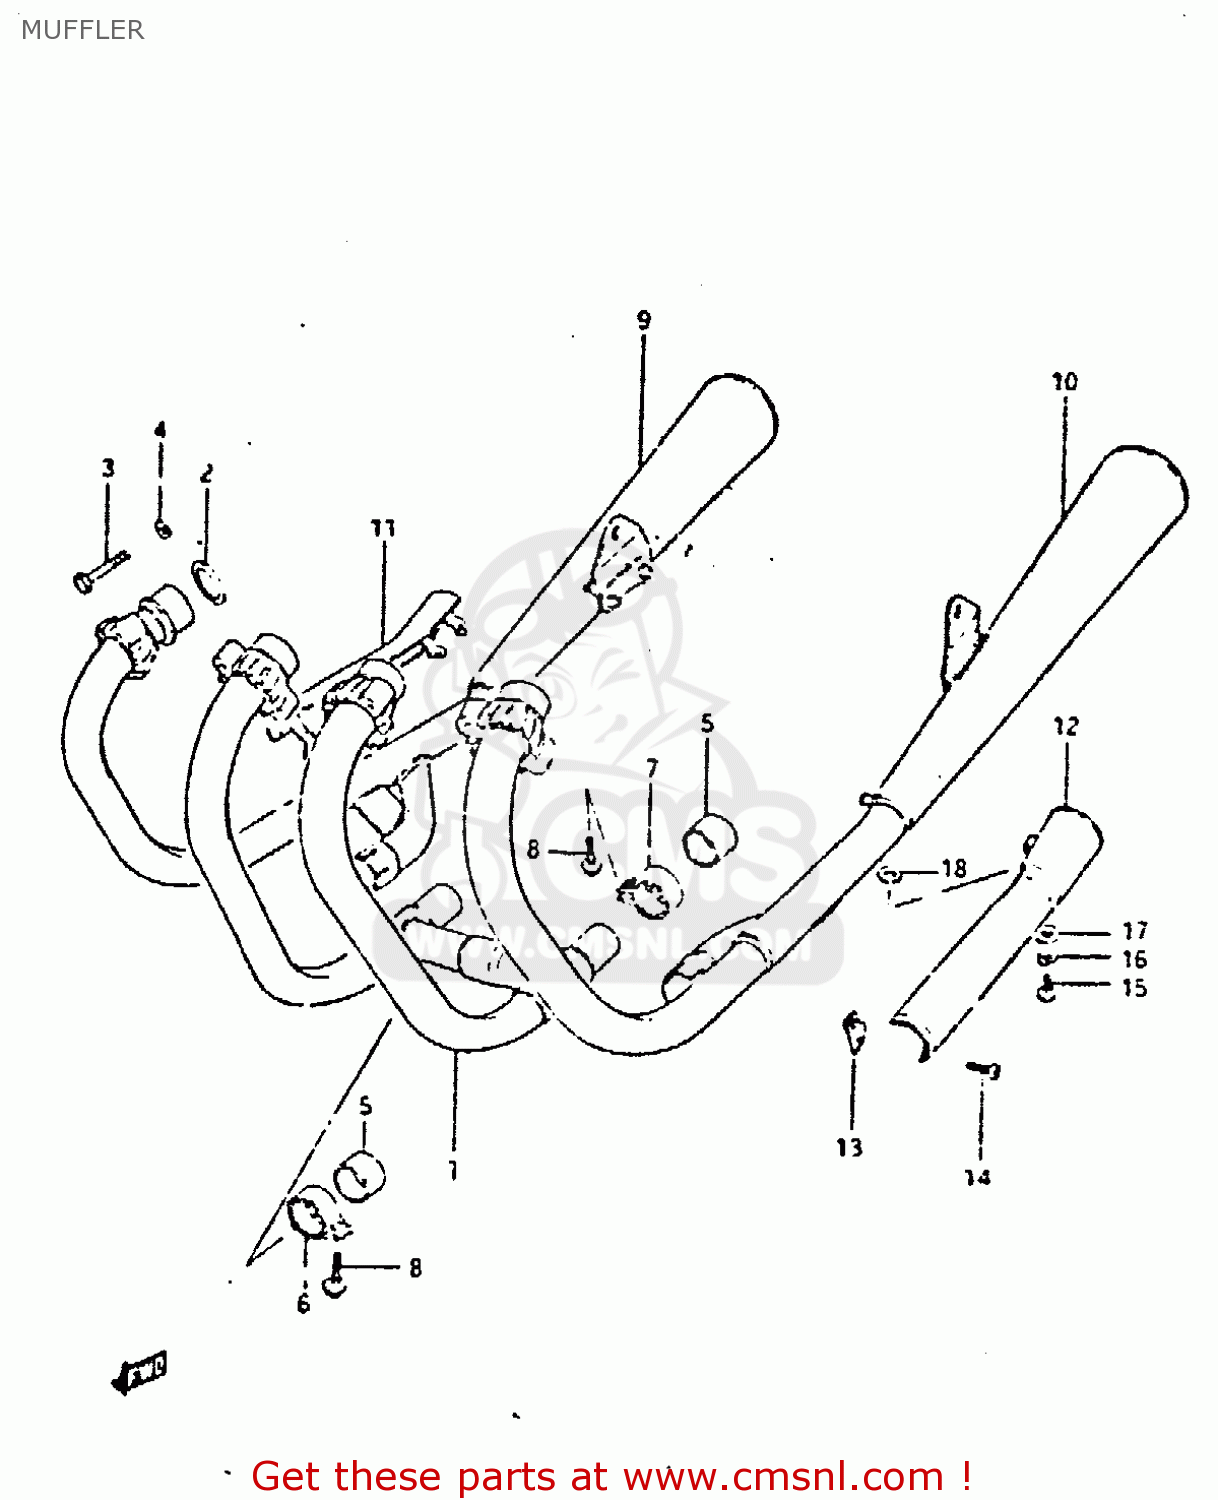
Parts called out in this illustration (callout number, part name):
1	PIPE,EXHAUST CTR
2	GASKET,EXHAUST PIPE (NAS)
3	BOLT 8X40
4	LOCK WASHER
5	CONNECTOR,MUFFLER
6	CLAMP,MUFFLER CONNECTOR,R
7	CLAMP,MUFFLER CONNECTOR,L
8	BOLT
9	MUFFLER ASSEMBLY
10	MUFFLER ASSEMBLY
11	COVER,MUFFLER,RIGHT
12	COVER,MUFFLER,LEFT
13	CLAMP,MUFFLER COVER
14	SCREW 5X20
15	SCREW 6X12
16	LOCK WASHER
17	WASHER
18	GASKET 6.2X12X1.5 (MCA)
